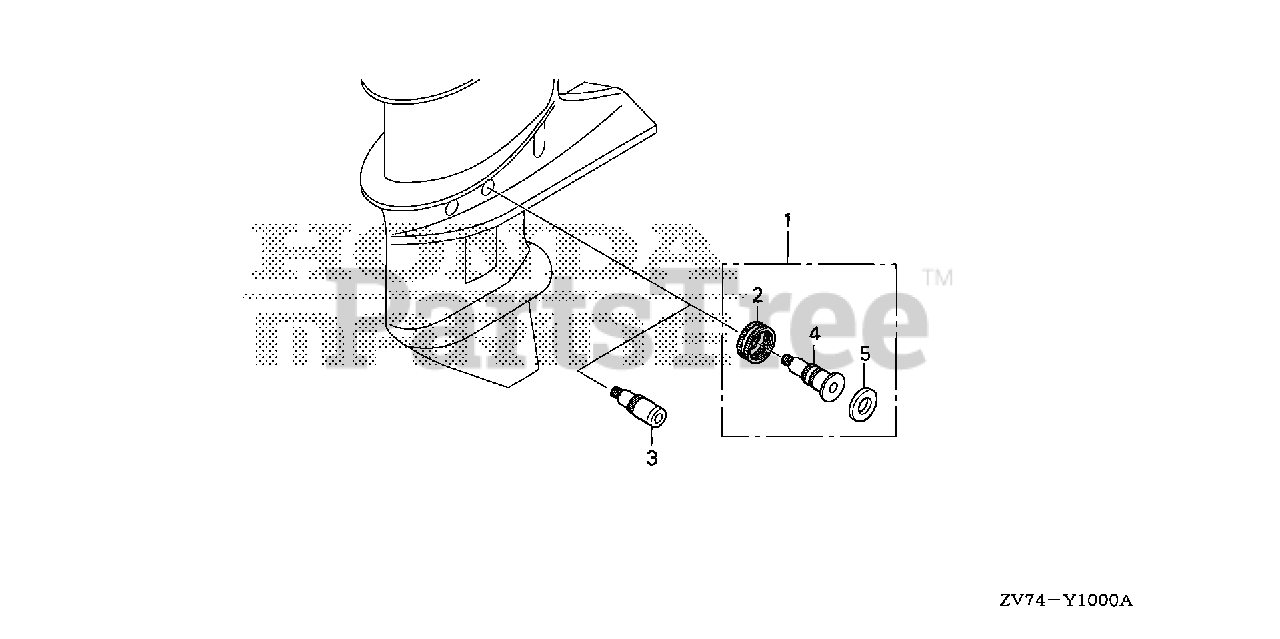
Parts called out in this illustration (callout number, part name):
1	JOINT KIT, WATER HOSE
2	NUT, WATER MOUTH
4	JOINT, WATER HOSE
5	SEAT, WATER MOUTH
